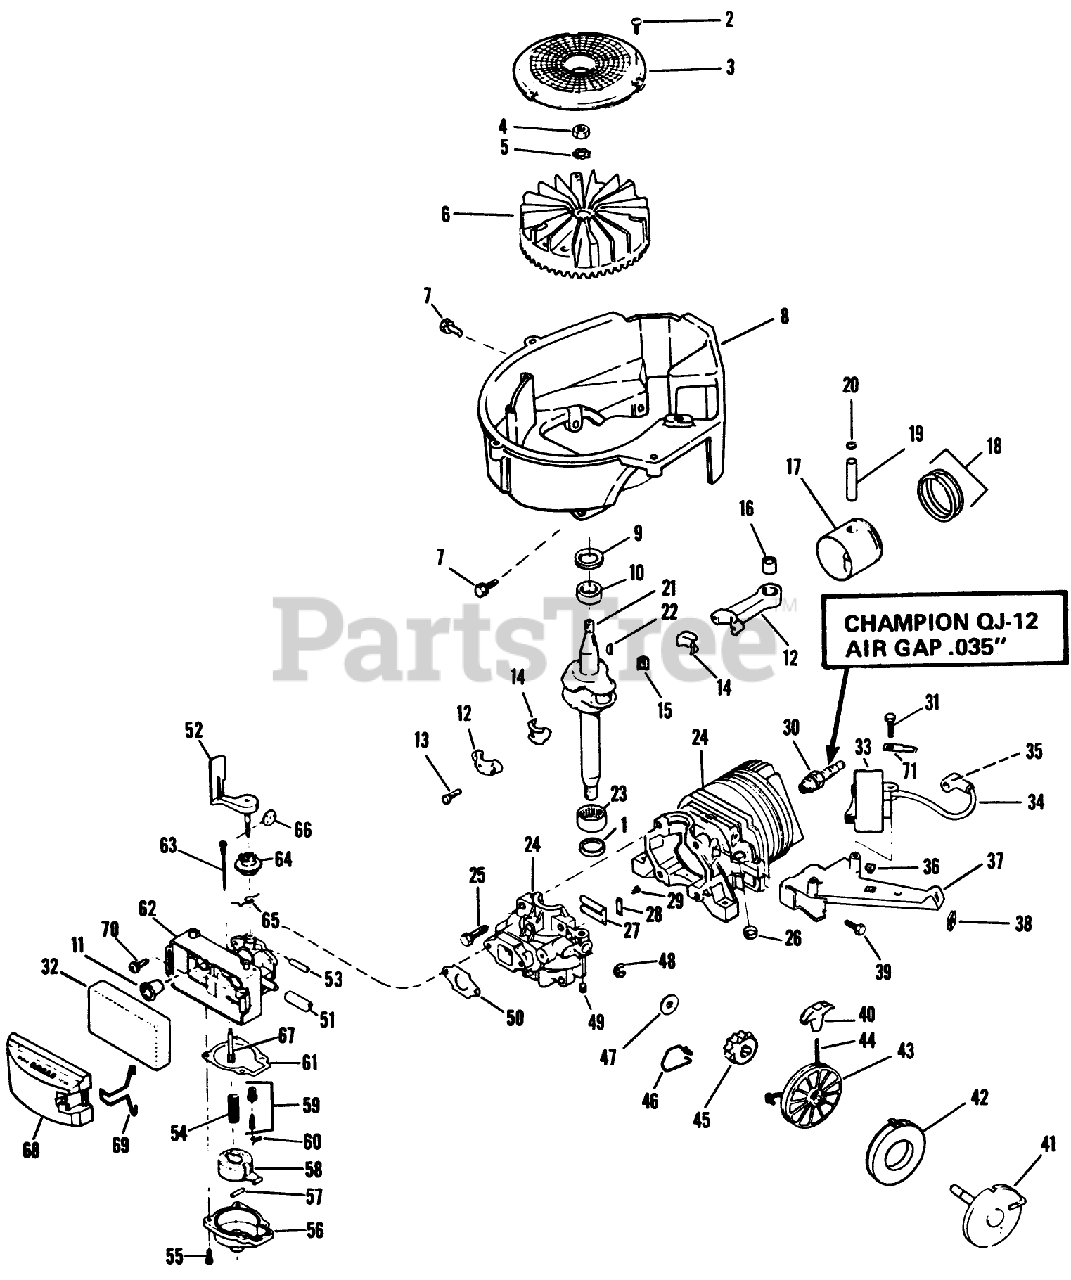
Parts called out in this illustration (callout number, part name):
1	SEAL-OIL
2	SCREW F
5	Lockwasher
7	SCREW-SEMS
8	SHRD BASE & EYELET
10	BEARING V
13	SCREW-HSH
14	LINER ASM
16	BEARING AY F
20	RING-RETAINING
22	KEY
23	BEARING V
25	SCREW S
26	PLUG-CORE VF
28	PLATE-BACKUP, REED
34	HT LEAD&COVER XEV
36	NUT-CLIP
38	NUT - SPEED S
40	HANDLE STARTER S
43	PULLEY STARTER S
46	SPRING F
47	WASHER S
50	GASKET CARB S
51	GAS LINE
52	AIR VANE&SHAFT S
53	TUBING PRIMER S
54	FILTER-FUEL VS
55	SCREW-HH
62	CARB BODY S
63	NEEDLE ADJ. AY S
64	COLLAR-ADJUST, AIRVANE
65	SPRING-THRO. S
66	DISC S
69	RETAINER-COVER, FILTER
70	SCREW
71	TERMINAL S
